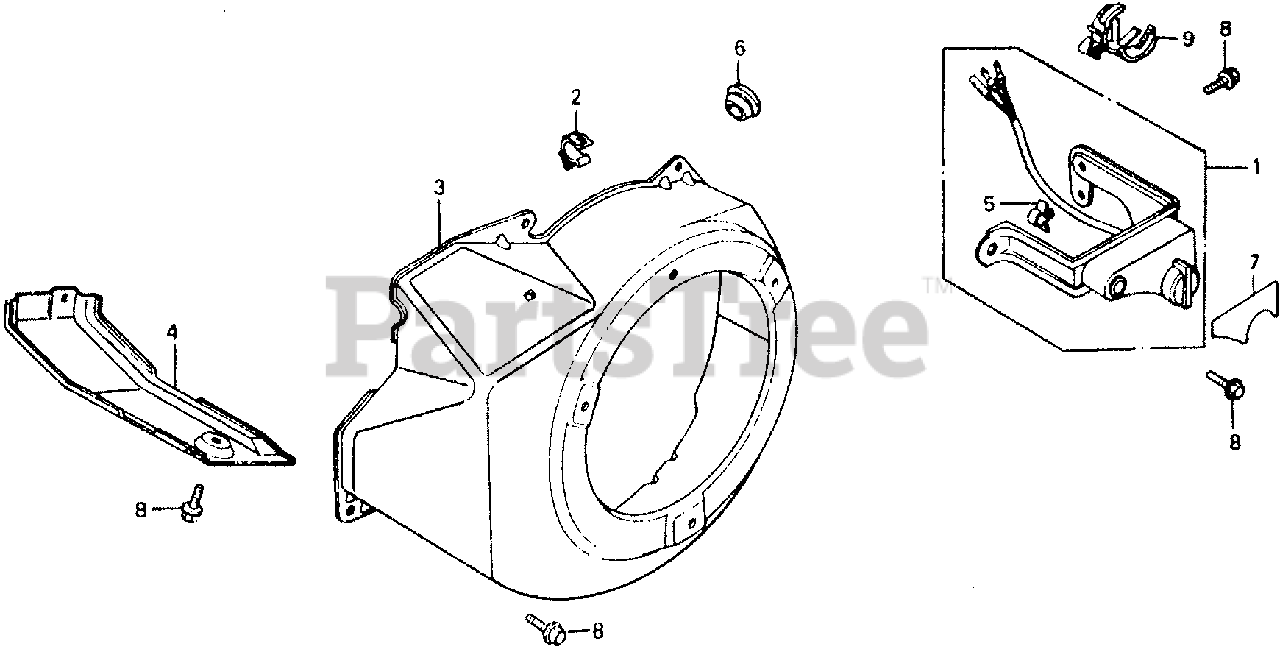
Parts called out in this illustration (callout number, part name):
1	ALERT UNIT, OIL
2	CLIP, TUBE
3	COVER, FAN *R8* (BRIGHT RED)
3	COVER, FAN *R280* (POWER RED)
4	SHROUD (NOT AVAILABLE)
5	CLIP, IGNITION WIRE (8MM)
6	GROMMET, DRAIN HOLE
7	MARK, OIL ALERT (EXTERNAL)
8	BOLT, FLANGE (6X12) (CT200)
9	CLIP, WIRE HARNESS
